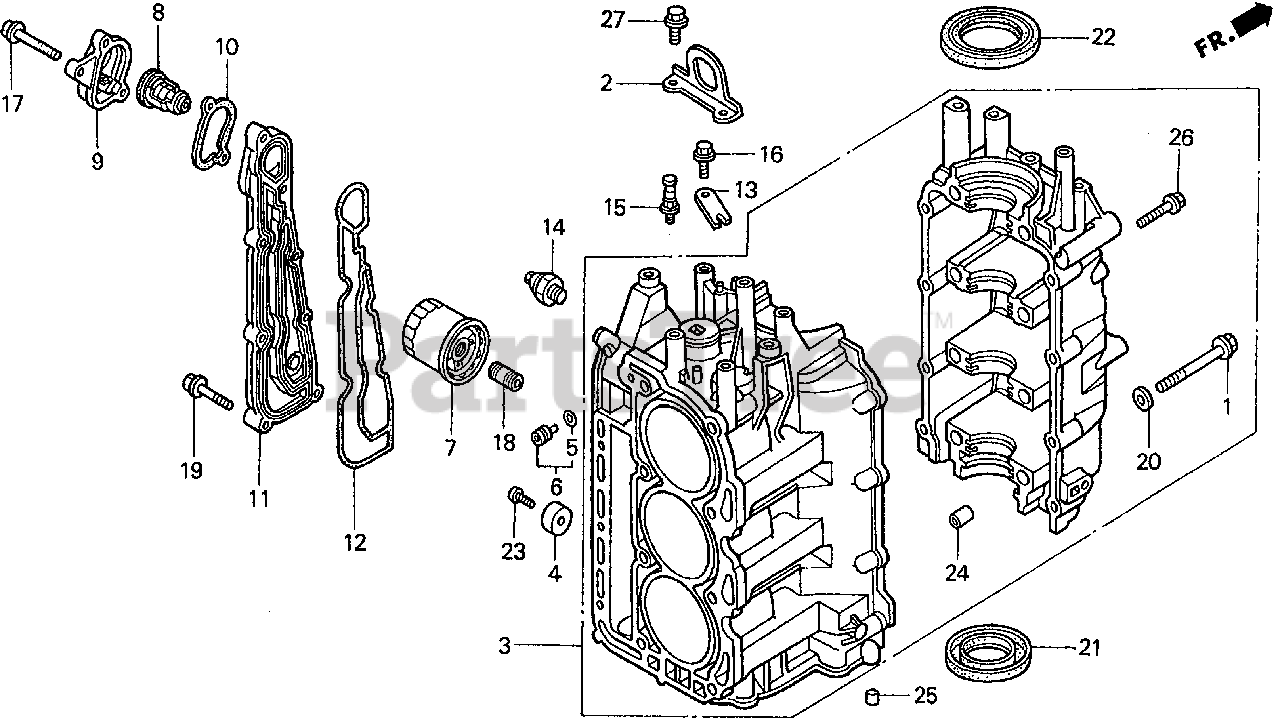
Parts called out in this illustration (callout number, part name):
1	BOLT, FLANGE (8X85)
2	HANGER, ENGINE
3	BLOCK ASSY., CYLINDER *NH8* (DARK GRAY)
4	METAL, ANODE
5	O-RING (4.8X1.9)
6	ORIFICE ASSY., OIL PASSAGE
7	FILTER, OIL
8	THERMOSTAT ASSY. (72 DEGREES C)
9	COVER, THERMOSTAT *NH8* (DARK GRAY)
10	GASKET, THERMOSTAT COVER
11	COVER, WATER *NH8* (DARK GRAY)
12	GASKET, WATER JACKET COVER
13	PLATE, SHIFT SHAFT
14	SWITCH ASSY., OIL PRESSURE (DENSO)
15	BOLT, TIMING BELT ADJUST SPRING
16	BOLT, FLANGE (6X12)
17	BOLT, FLANGE (6X35)
18	HOLDER, OIL FILTER
19	BOLT, FLANGE (6X22)
20	WASHER, PLAIN (8MM)
21	OIL SEAL (35X52X8)
22	OIL SEAL (44.5X60.5X8) (NOK)
23	SCREW, PAN (6X18)
24	PIN, DOWEL (10X12)
25	PIN, DOWEL (6X10)
26	BOLT, FLANGE (6X40)
27	BOLT, FLANGE (8X18)
